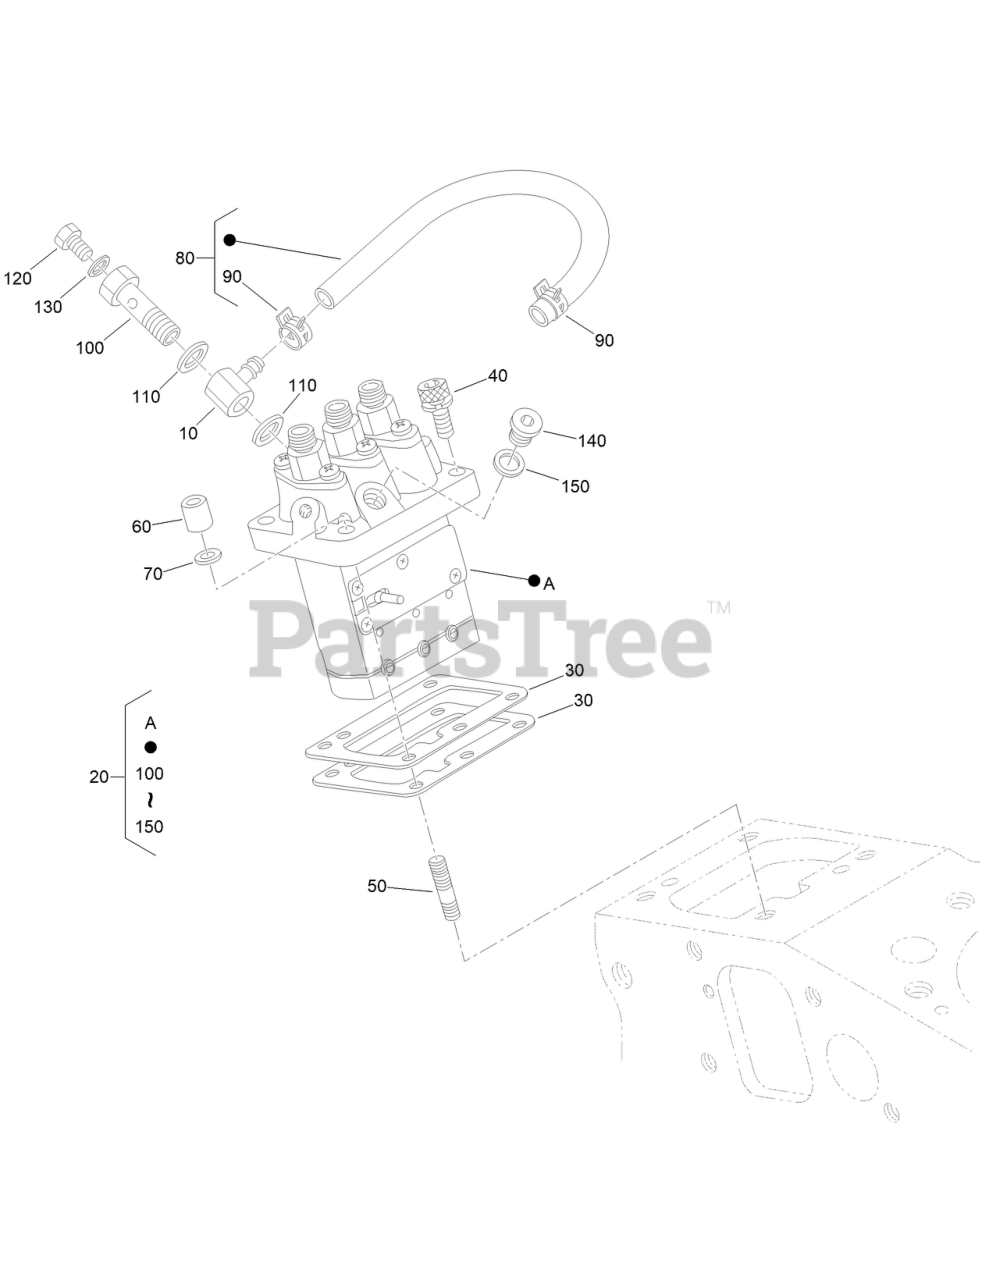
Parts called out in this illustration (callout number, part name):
10	JOINT,EYE
20	INJECTION PUMP ASM
30	SHIM-INJECTION (0.175MM)
30	SHIM-INJECTION (0.20MM)
30	SHIM-INJECTION (0.25MM)
30	SHIM-INJECTION (0.30MM)
30	SHIM-INJECTION (0.35MM)
40	BOLT-HEX SOC HD
60	NUT-CAP
70	WASHER,SPRING LOCK
80	FUEL PIPE ASM
90	CLIP-PIPE
100	SCREW-HOLLOW
110	GASKET
120	SCREW
130	GASKET
150	GASKET
